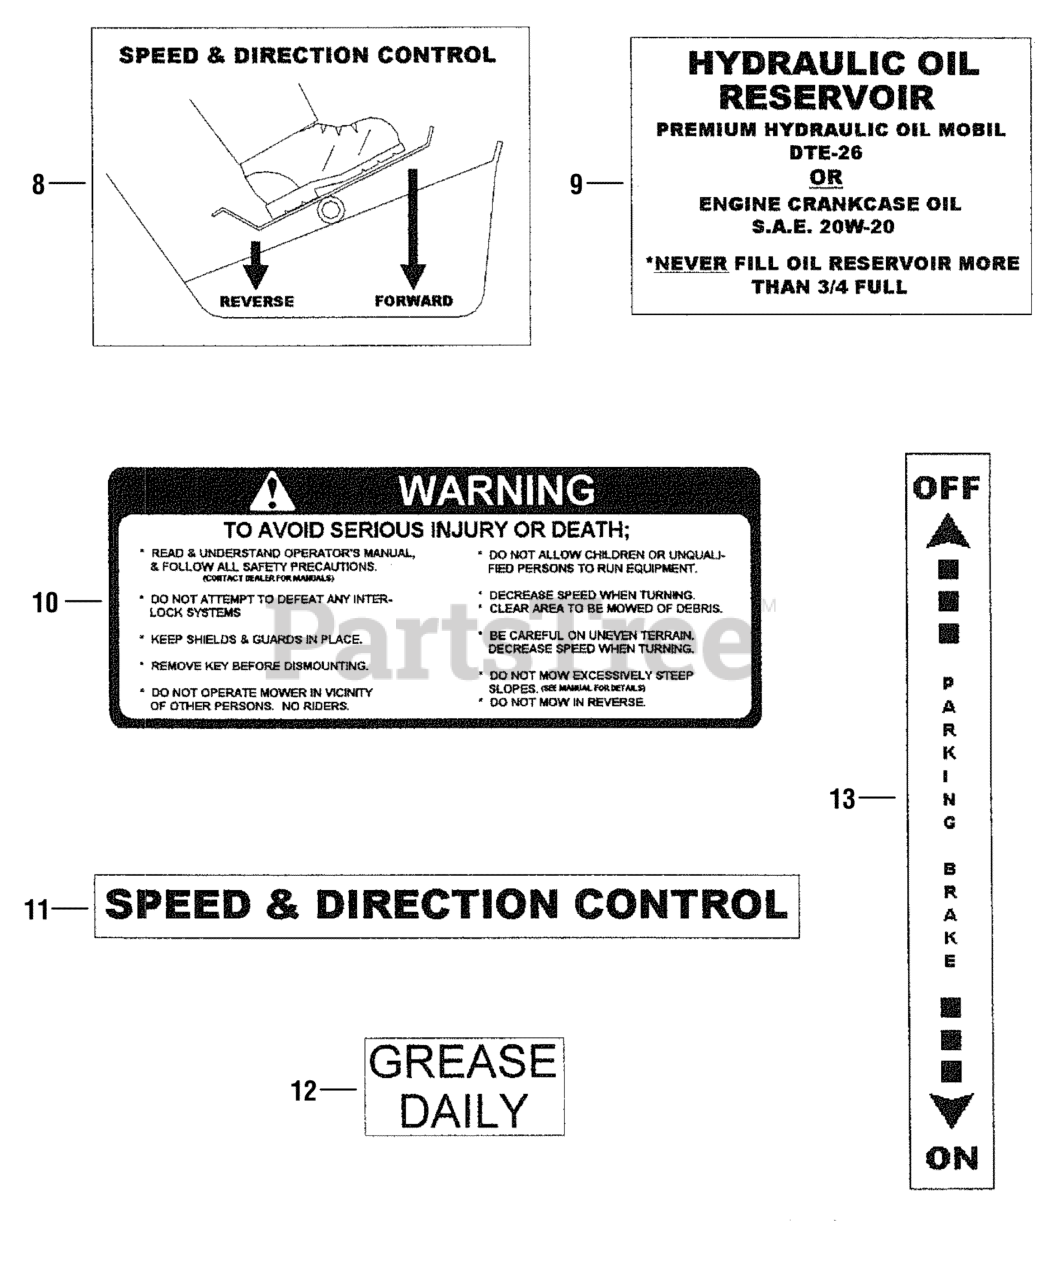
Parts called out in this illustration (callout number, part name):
8	Decal, Control Pedal
9	Decal, Hydro Oil
10	Decal, Warning
12	Decal, Grease Daily
13	DECAL, PARKING BRAKE-RIDER
